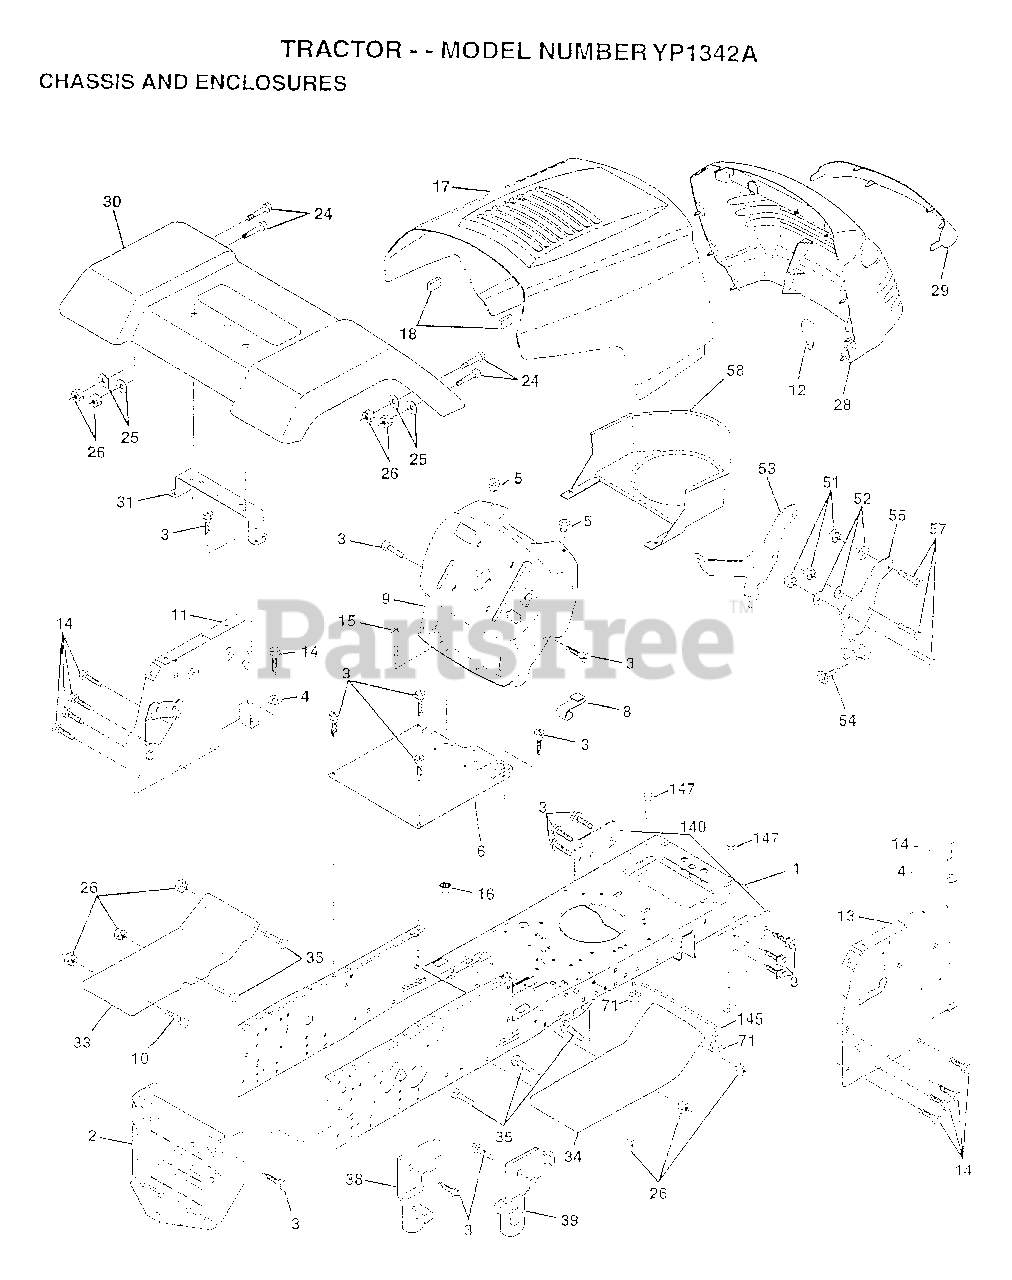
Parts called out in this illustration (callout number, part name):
1	CHASSIS ASM
3	SCREW
4	WASHER
5	BUMPER-HOOD/DASH
6	SADDLE SLKSCR FLAT LT 6SP PEER
8	CLIP.RETAINER
9	DASH SILKSCREEN
11	"PANEL-DASH,LH"
12	CLIP.TINNERMAN
14	SCREW LT
15	SCREW
24	BOLT
25	WASHER
26	NUT
28	GRILL
29	DECAL.LENS.YP.EUR
30	FENDER ASM LT W/S
31	BRKT FENDER
33	FOOTREST PNT LH
34	FOOTREST.RH.LT/GT
35	BOLT
38	BRACKET ASM LH
39	BRACKET ASM RH
51	NUT
52	WASHER 9/32 X 7/8 X 16 GA.
53	BRACKET.GRILLE.LH
55	BRACKET.GRILLE.RH
58	AIR DUCT
140	BRKT SUSPENSION
145	"ROD POVOT,CHASSIS"
147	BOLT LT
